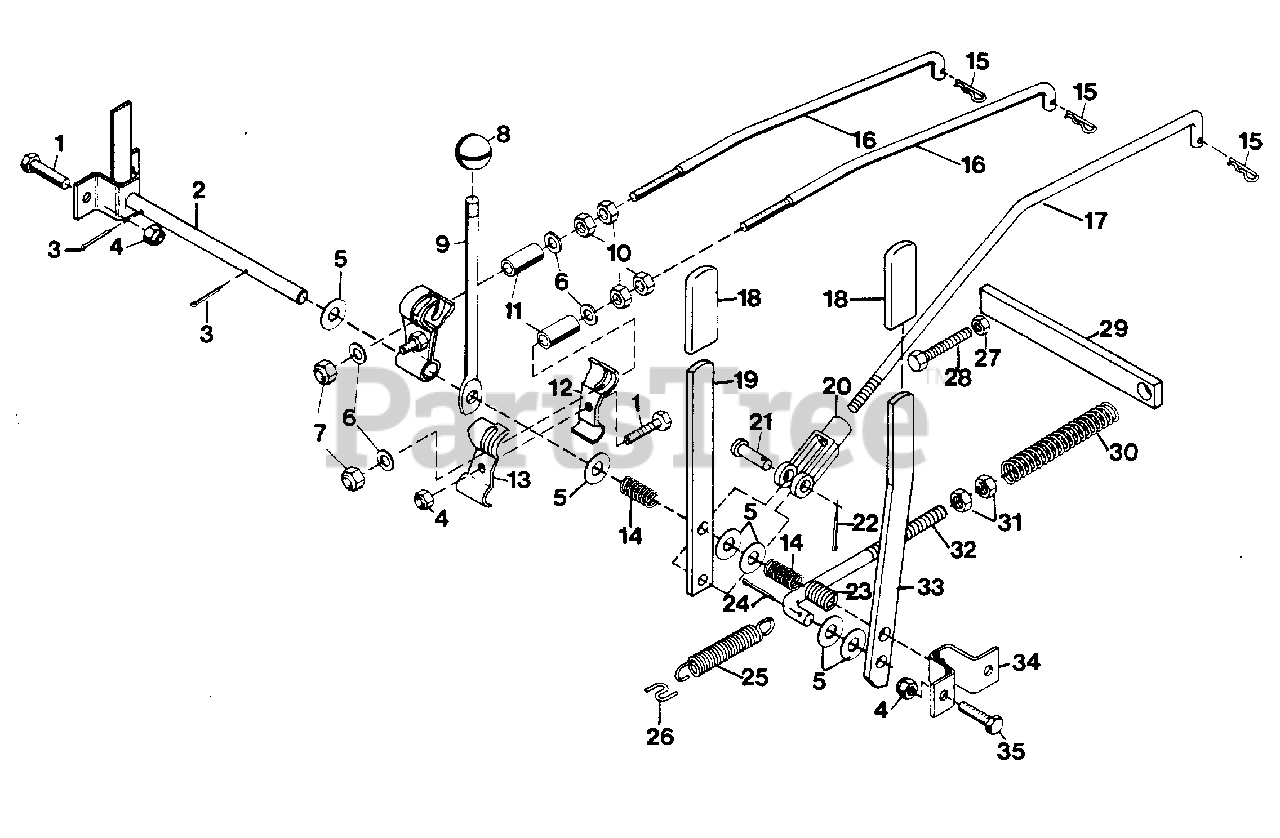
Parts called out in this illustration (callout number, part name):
1	BOLT, HEX 5/16-18X.75
2	WELDMENT, CROSS SHAFT
3	PIN, COTTER .12X1.0
4	NUT, LOCK 5/16-18
5	WASHER, FLAT .531X1.06X.095
6	WASHER, FLAT .438X1.00X.083
7	NUT, LOCK 3/8-16
8	KNOB, CONTROL
9	LEVER, SHIFT
10	NUT, JAM 3/8-16
11	BUSHING, .400X.500X1.65
12	ARM, SHIFTER R.H.
13	ARM, SHIFTER L.H.
14	SPRING, COMP. 2.75X.625X34
15	PIN, COTTER HAIR
16	ROD, SHIFT
17	ROD, 2-SPEED
18	GRIP, HANDLE
19	LEVER, HI-LO SHIFT
20	CLEVIS, 3/8-24 ADJUSTABLE
21	PIN, CLEVIS .375X.948
22	PIN, COTTER .09X.75
23	SPRING, COMP. 1X.78X338
24	PIN, COTTER .125X1.25
25	SPRING, EXTENSION 5.5X.5X20 RATE
26	CLIP, SPRING
27	NUT, HEX 3/8-16
28	BOLT, HEX 3/8-16X2.50
29	SPRING, PTO CLUTCH
30	SPRING, COMP.(PTO LOADING)
31	NUT, JAM 1/2-13 HEX
32	ROD, LIFT
33	LEVER, PTO CONTROL
34	BRACKET, CROSS SHAFT
35	BOLT, HEX 5/16-18X1.00
